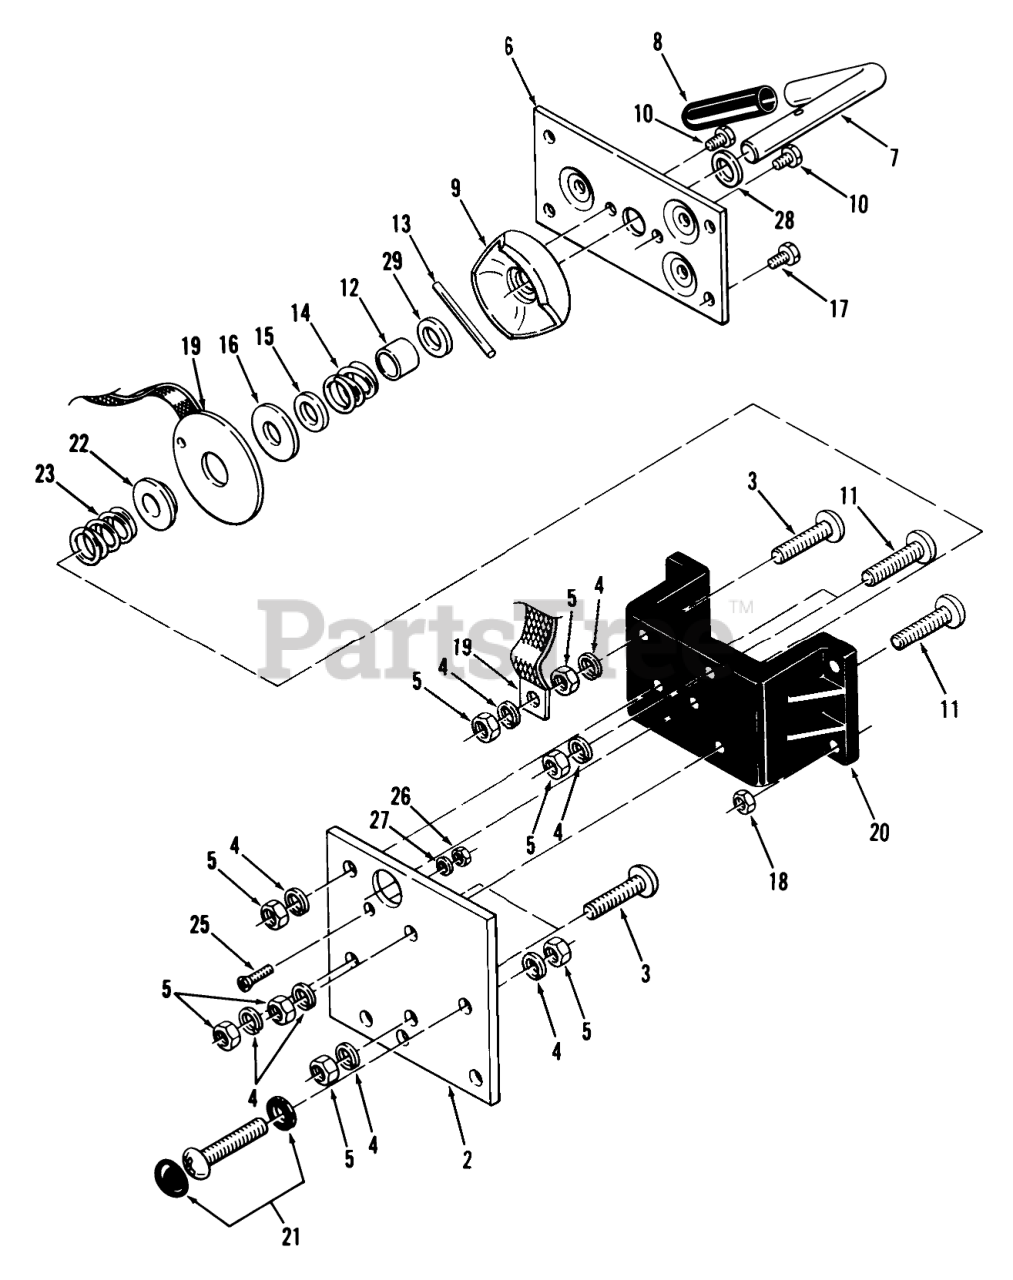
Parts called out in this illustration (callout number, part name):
1	Power Disconnect Assembly
2	Terminal Block
3	Screw 1/4-20 X 3/4 Brass
4	Washer
5	Nut, 1/4-20
6	Disconnect Plate
7	Switch Handle
8	Hand Grip
9	Plastic Cam
10	Self Tapping Screw #6 X 3/8
11	Bolt, Copper Contact
12	Sleeve
13	ROLL PIN 1/8 X 1 1/2
14	Spring
15	Washer
16	Fiber Washer
17	Screw 6-32 X 1/2
18	Nut #4-40
19	Contact Disc
20	Switch Housing
21	Plastic Cover & Washer
22	Fiber Bushing
23	SPRING
25	Screw
26	Nut #4-40
27	#4 Lockwasher
28	Neoprene Washer 5/16
29	LOCKWASHER
